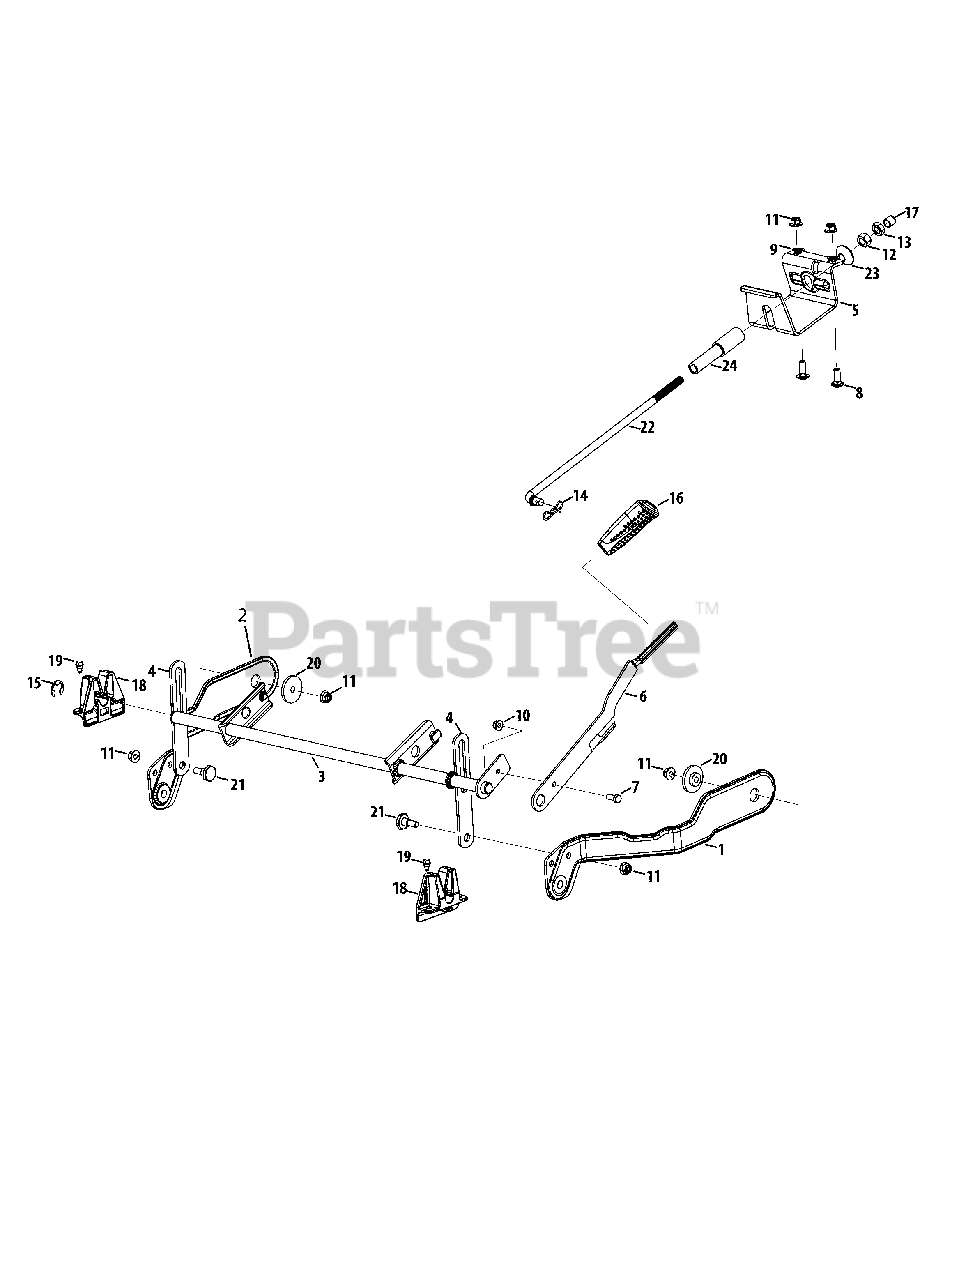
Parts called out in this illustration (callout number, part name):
1	PLATE, Deck Lift, RH
2	PLATE, Deck Lift, LH
3	ASSEMBLY, Deck Lift Shift
4	PLATE, Lift Link
5	BRACKET, Rod Support Mounting
6	HANDLE, Deck Lift
7	SCREW, 5/16-18 X .75, Hex Cap
8	BOLT, 3/8-16 X 1.00, Carriage
9	NUT, 3/8, Push
10	NUT, 5/8-18 Hex Flange
11	NUT, 3/8-16, Flanged Lock, GR5, Zinc/Clear
12	NUT, 1/2-13, Hex Nylock
13	NUT, 1/2-13, Hex
14	PIN, Bow Tie Cotter
17	END CAP, Lift Rod
18	BRACKET, Deck Lift
19	BOLT, Shoulder, 1/4-20 x 1/2"
20	SPACER, Shoulder -S
21	SCREW, 3/8-16, Shoulder
22	ROD, Deck Front Lift
23	CUP, Lift Pivot
24	SLEEVE, .55 ID X 4.50 LG
